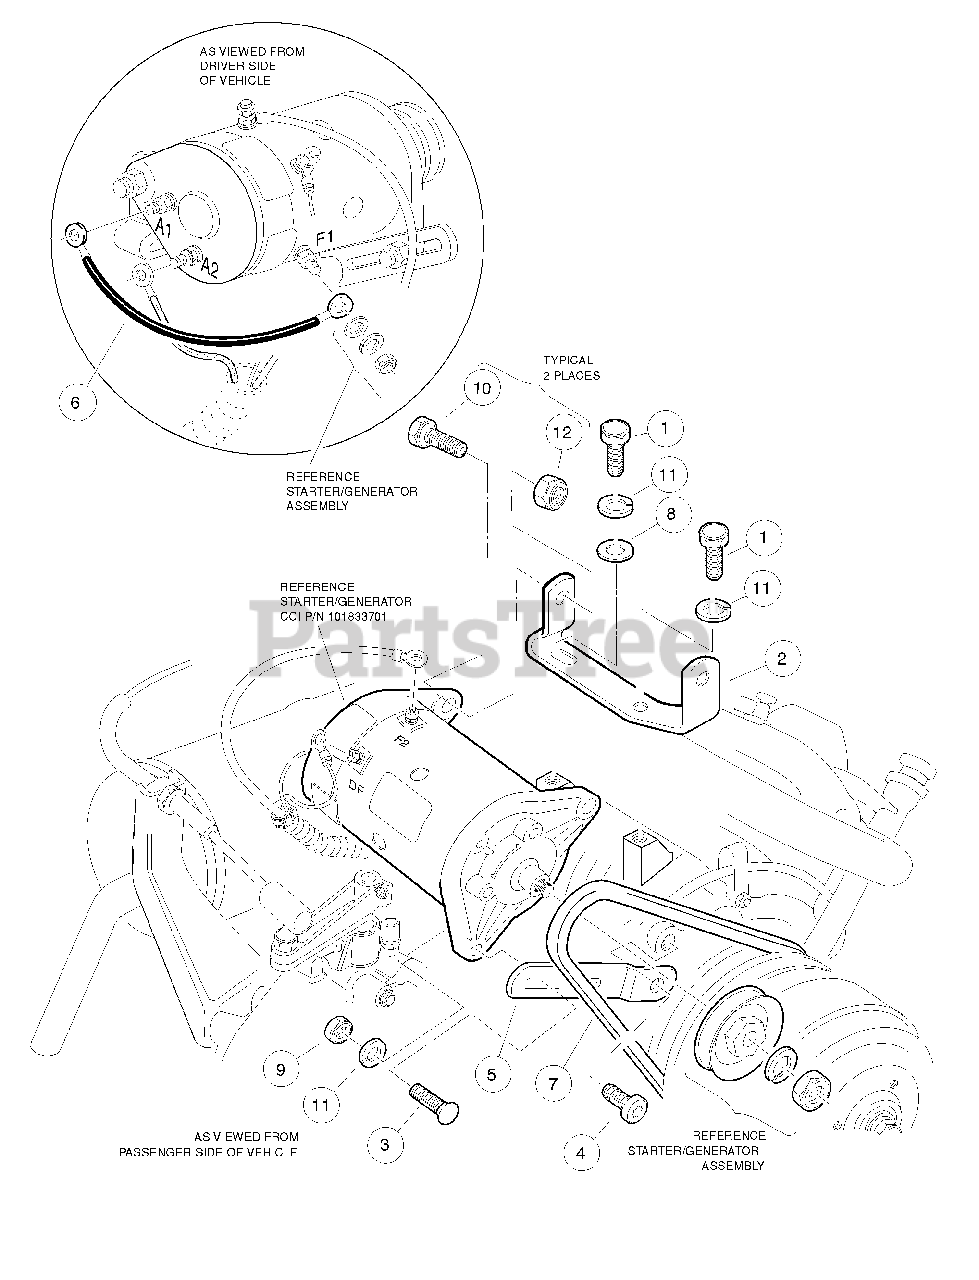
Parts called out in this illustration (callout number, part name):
1	Screw, M8-125 X 22 Hex-Head
2	Bracket, Starter/Generator Mounting
3	Bolt, Carriage, 5/16-18
4	Screw, M8-1.25 X 18mm Torx
5	Bracket, Starter/Generator Adjustment
6	Wire Assy, #6 Green
8	Washer, 5/16 Type A Flat
9	Nut, 5/16-18 Hex
10	Screw, Cap-hex Hd 3/8-16x1.25
11	Lockwasher, 5/16 Split
12	Locknut, 3/8-16 Hex
